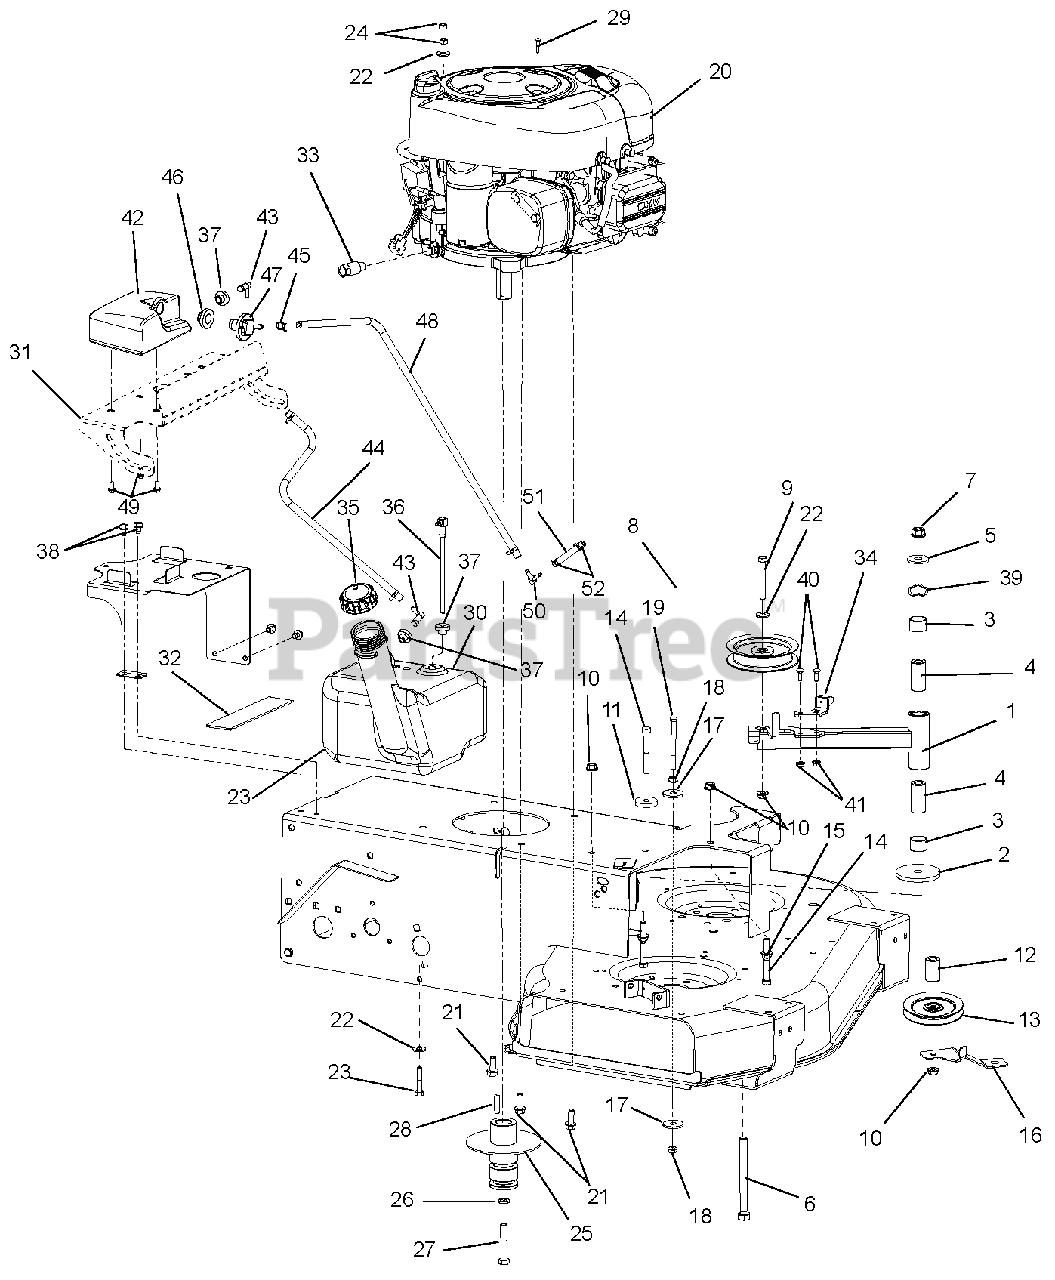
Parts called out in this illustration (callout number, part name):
1	Weldment, PTO Idler Arm
2	Washer, Flat .531 x 3.00 x .25
3	Bearing 1.00 x 1.12 x .75
4	Bushing, Spacer .505/.500 x .999/.996 x 2.05/2.03
5	Washer, Flat Steel .511 x 1.44 x .125
6	Bolt, Hex .50-13 x 5.50
7	Nut, Locking Top Flange .50-13
8	Idler, Flat .38 x 4.00 x 1.06
9	Bolt, Hex .38-16 x 2.75
10	Nut, Locking Top Flange .38-16
11	Washer, Flat Steel .406 x 1.50 x .245
12	Spacer, .437 x 1.00 x 1.23
13	Idler, 4.00 x .38
14	Bolt, Hex .38-16 x 3.00
15	Nut, Flange .375-16
16	Bracket, Idler Brace
17	Washer, Flat Steel .406 x 1.375 x .135
18	Nut, Spin-Lock Flange .312-18
19	Bolt, Hex .31-18 x 3.50
20	Engine, Briggs & Stratton, 14.5Hp
21	Screw, Hex Washer Head Tapping .38-16 x 1.00 (Torque = 374 - 562 lbf-in (42.26 - 63.5 Nm))
22	Washer, Flat Steel .38 x .875 x .083
23	Bolt, Hex .31-18 x 1.75
24	Nut, Locking Center .31-18
25	Pulley, Deck Drive
26	Washer, Locking .44 x .109
27	Bolt, Hex .44-20 x 2.50 (Torque = 394 - 590 lbf-in (44.52 - 66.66 Nm))
28	Key, Square .25 x 1.25 x .25
30	Tank, Fuel (Serials 101 - 2499)
31	Bracket, Gas Tank Mount (Serials 2500 and up)
32	Pad, Gas Tank
33	Drain, Oil
34	Brake Pad, Wedge (Serials 000101 - 011195)
35	Fuel Cap (Serials 101 - 2499)
36	Assembly, Pickup, Fuel 6.5L
37	Bushing, Flange .375 x 1.062 x .625 (Serials 101 - 2499)
38	Screw, Tapping .31-18 x .50 Hex Washer Head
39	Washer, Wave 1.09 x 1.37 x .016
40	Bolt, Round Head Square Neck .25-20 x .75
41	Nut, Locking-Top-Flange .25-20
42	Zoom/WAW Exp. Tank
43	Fitting, 90 Deg. Fuel (Serials 2500 and up)
44	Fuel Line (Serials 2500 and up)
45	Hose Clamp (Serials 2500 and up)
46	Grommet, Remote Vent (Serials 2500 and up)
47	Vent, Roll-Over (Serials 2500 and up)
48	Fuel Line (Serials 2500 and up)
49	Bolt, Serrated Hex Flange Washer Head .312-18 x .50 (Serials 2500 and up)
50	Adapter (Serials 2500 and up)
51	3/16 ID Fuel Line (Serials 2500 and up)
52	Hose Clamps (Serials 2500 and up)
